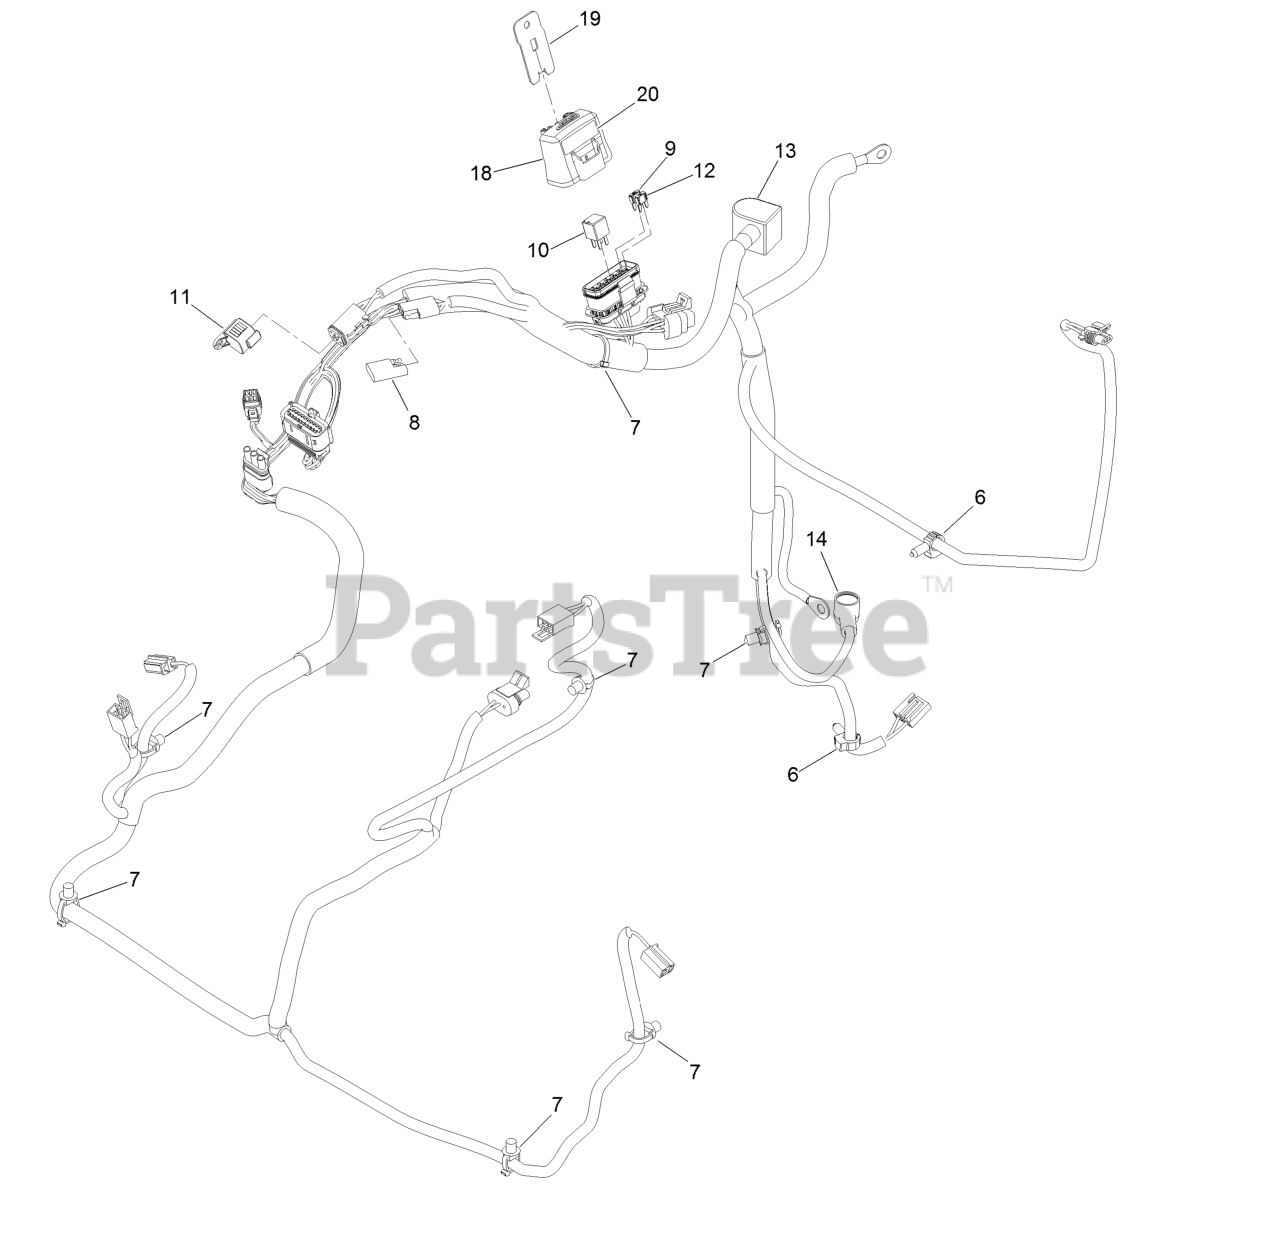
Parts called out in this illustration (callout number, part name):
6	Clip-Harness
7	Clip-Tie
8	Cap-Plug
9	Fuse-Mini Blade, 20 Amp
10	Relay-Micro
11	Cap-Plug, 6 Way
12	Fuse-Mini Blade, 15 Amp
13	Insulator-Battery
14	Insulator-Solenoid
18	Cover-Block, Fuse
19	Clip-Mounting
20	Decal-Fuse
